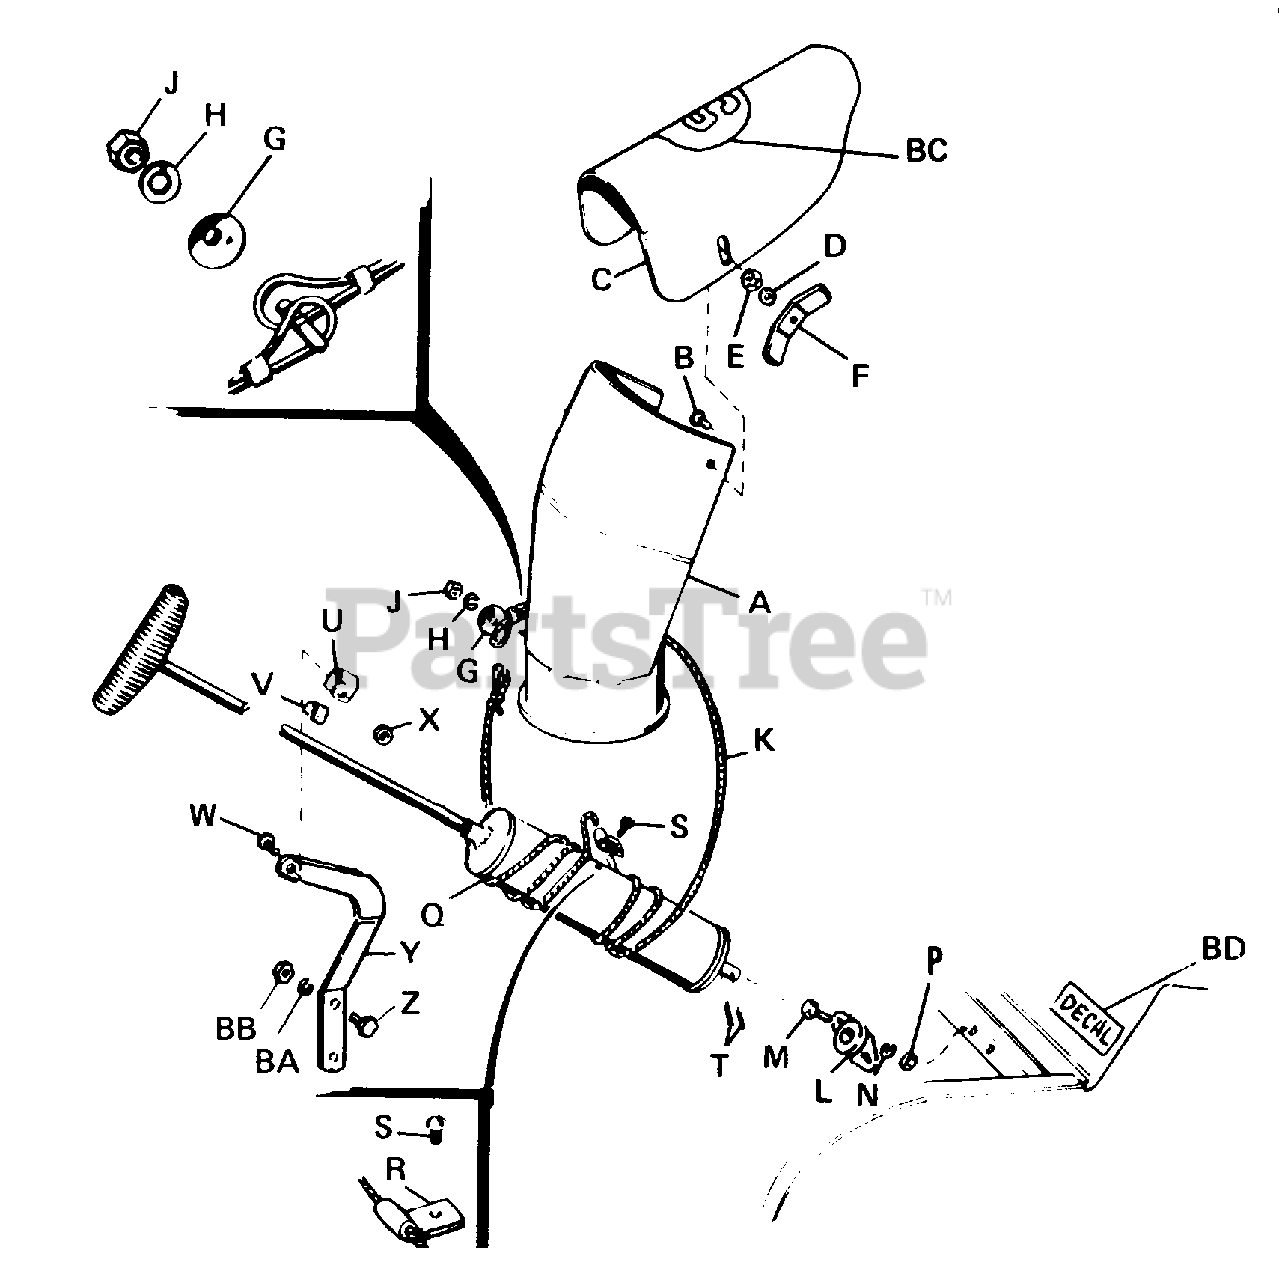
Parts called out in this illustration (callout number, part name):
A	Spout Assembly
B	Carriage Bolt, 5/16"-18 x 3/4"
C	Spout Extension
D	Washer, Plain 3/8"
E	Washer, Lock 3/8"
F	NUT, Wing, 5/16-18
H	Washer, Lock 5/16"
J	Nut, Hex Full 5/16"-18
K	Cable Assembly
M	Capscrew, Hex, 1/4"-20 x 5/8"
N	Washer, Lock 1/4"
P	Nut, Hex, Full 1/4"-20
Q	Tube Assembly, Spout Control
R	Clamp (For service only)
S	Self-Tapping Screw, 1/4"-20 x 3/8"
T	Cotter Pin, 3/32" x 5/8"
V	Liner, Guide
W	Capscrew, Hex, 5/16"-18 x 1-1/2" lg.
X	Nut, Hex, Full, Lock, 5/16"-18
Y	Rod Guide Support
Z	Hex. Capscrew, 3/8"-16 x 1" lg.
BA	Lock Washer, 3/8"
BB	Hex. Nut, Full, 3/8"-16
BD	Decal Safety
